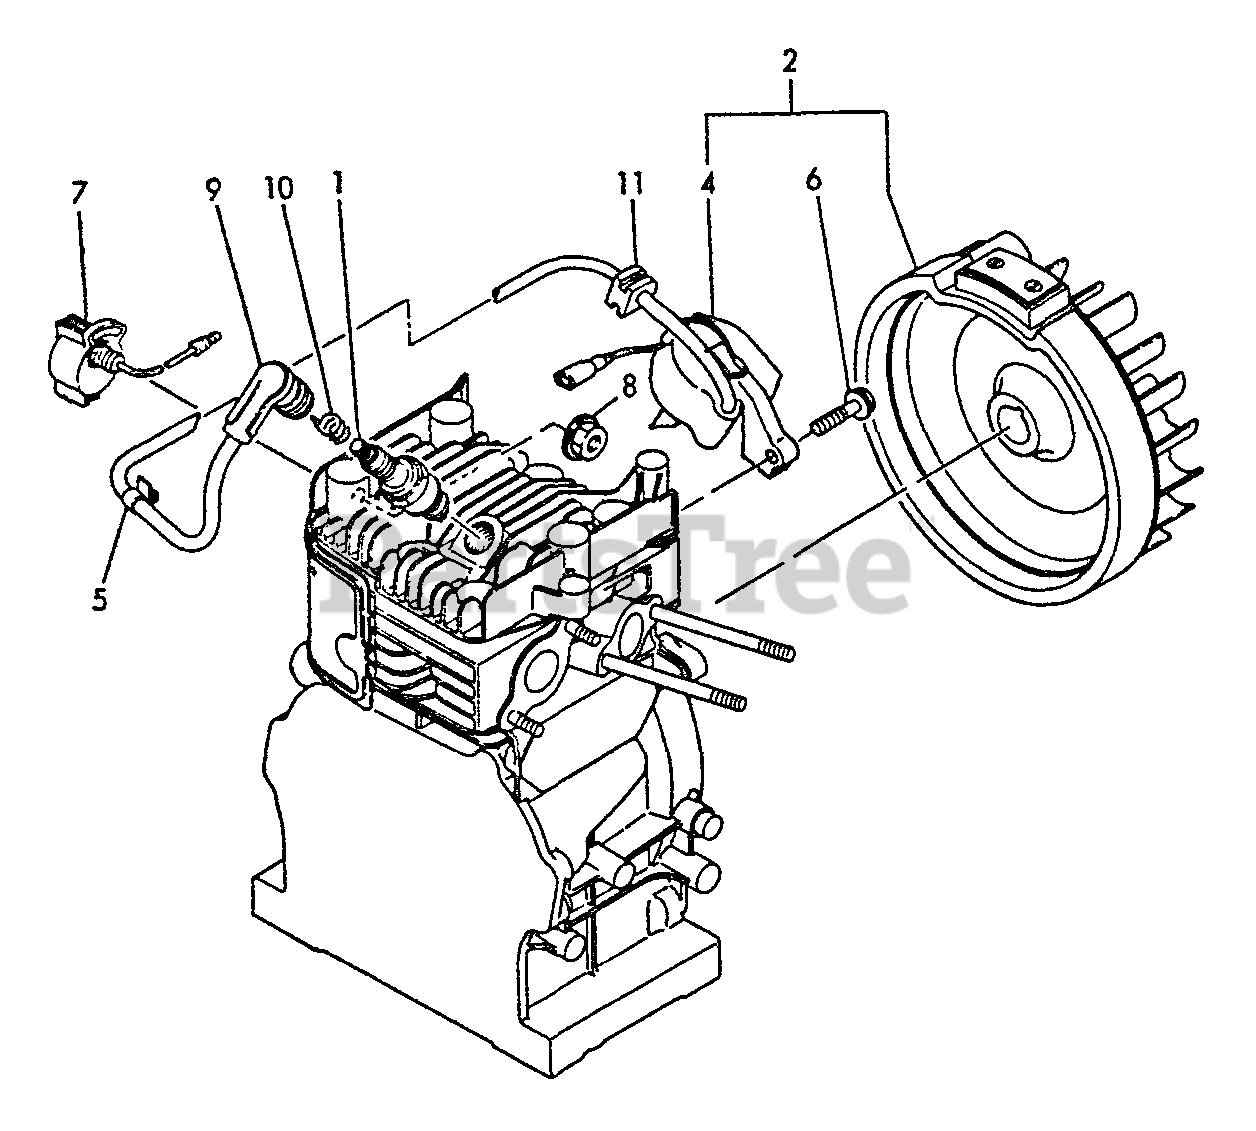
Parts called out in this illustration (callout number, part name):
1	SPARK PLUG
2	FLYWHEEL
4	COIL, IGNITION
5	CLAMP
6	BOLT - 6×30
7	SWITCH, STOP
8	U-NUT M8
9	CAP, PLUG
10	TERMINAL, SPARK PLUG CAP
11	GROMMET
